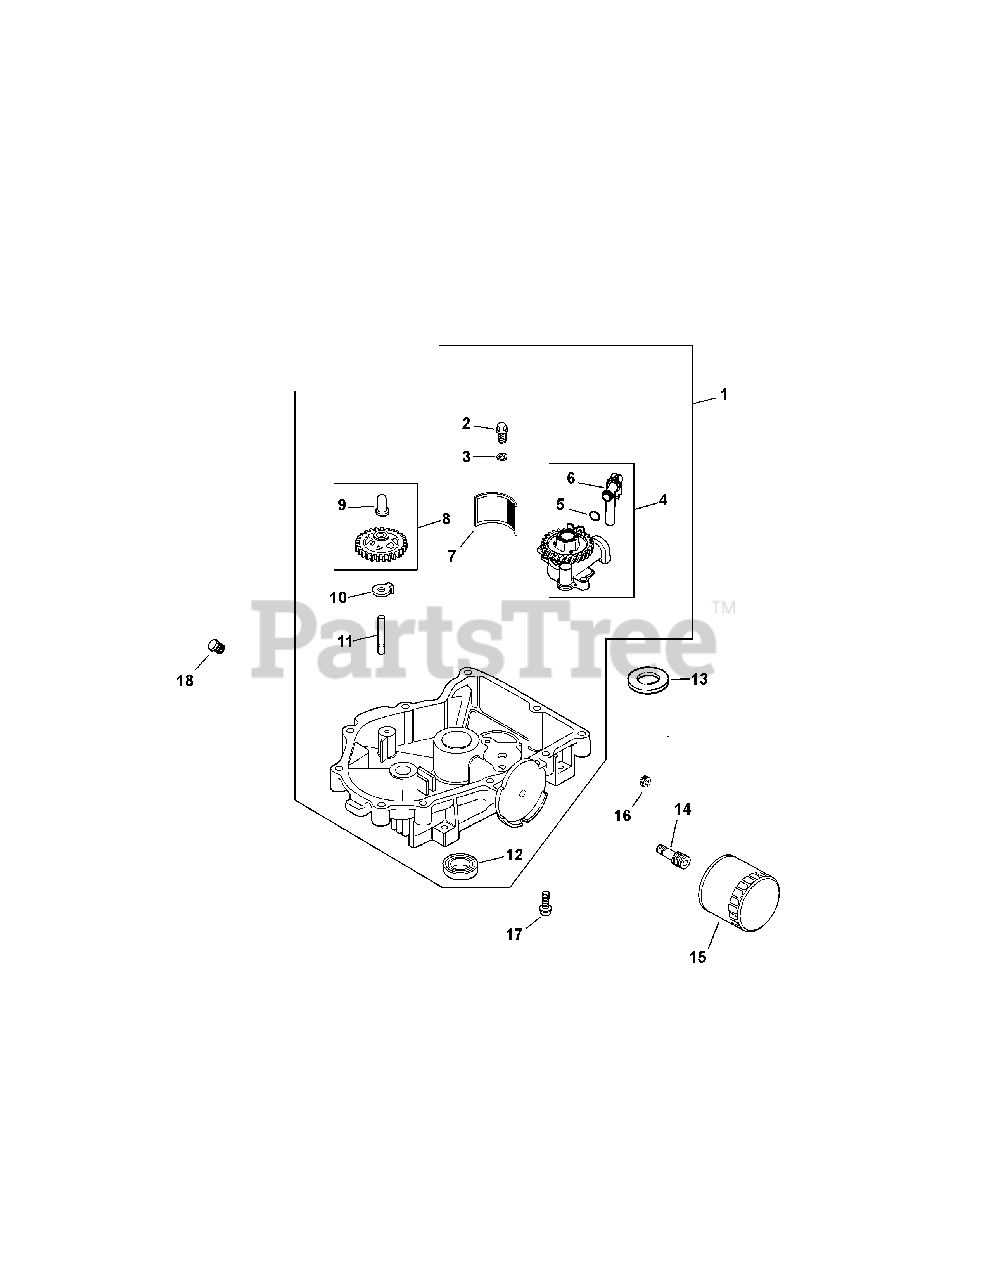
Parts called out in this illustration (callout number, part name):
1	OIL PAN ASSEMBLY (includes 2-12)
2	SCREW, FLG THD FRM M6X1.0X25
3	WASHER, FLAT 6 MM
4	KIT, OIL PUMP ASSEMBLY (includes 5, 6)
5	O-RING, OIL PICK-UP
6	KIT, OIL PICK-UP TUBE
8	KIT, GOVERNOR GEAR W/PIN (includes 9)
9	PIN, GOVERNOR REGULATING
11	SHAFT, GOVERNOR GEAR
12	OIL SEAL USE 25 032 06-S
14	NIPPLE, OIL FILTER
16	PLUG, PIPE CTSK 3/8''
17	SCREW, FLG M8X1.25X45
18	PLUG, HD PIPE 3/8''
